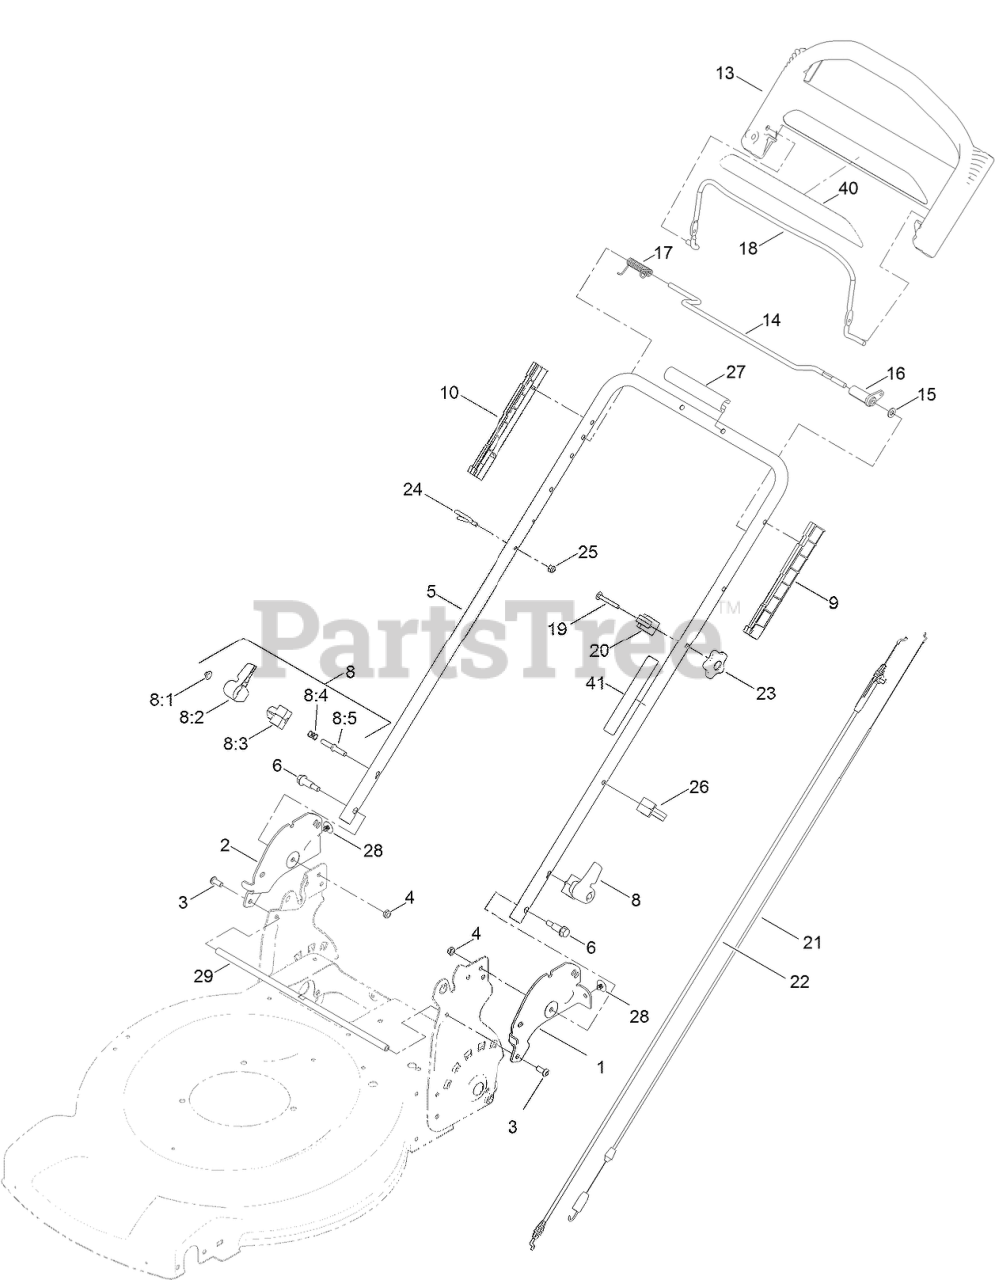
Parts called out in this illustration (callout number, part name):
1	PLATE-HANDLE, LH
2	PLATE-HANDLE, RH
3	SCREW-HSBH
4	NUT-LOCK, NI
6	BOLT-SHOULDER
8	QUICK RELEASE ASM
8:1	NUT-PUSH
8:2	LEVER
8:3	ANCHOR-SPRING
8:4	SPRING-COMPRESSION
8:5	ROD-RELEASE
9	GUIDE-LH
10	GUIDE-RH
13	HANDLE-CONTROL
14	BAR-CONTROL, TRACTION
15	WASHER-PLAIN
16	LEVER-TRACTION
17	Spring-Torsion
18	BAIL-BRAKE
19	SCREW-CARR
20	ANCHOR-CABLE
21	CABLE-TRACTION
22	CABLE-BRAKE
23	KNOB-HANDLE, LOCKING
24	GUIDE-ROPE
25	NUT-LOCK, NI
26	GUIDE-CABLE
27	HANDLE-COVER
28	CLIP-TREE
29	Rod-Stiffener
41	DECAL-TRACTION, ADJUST
